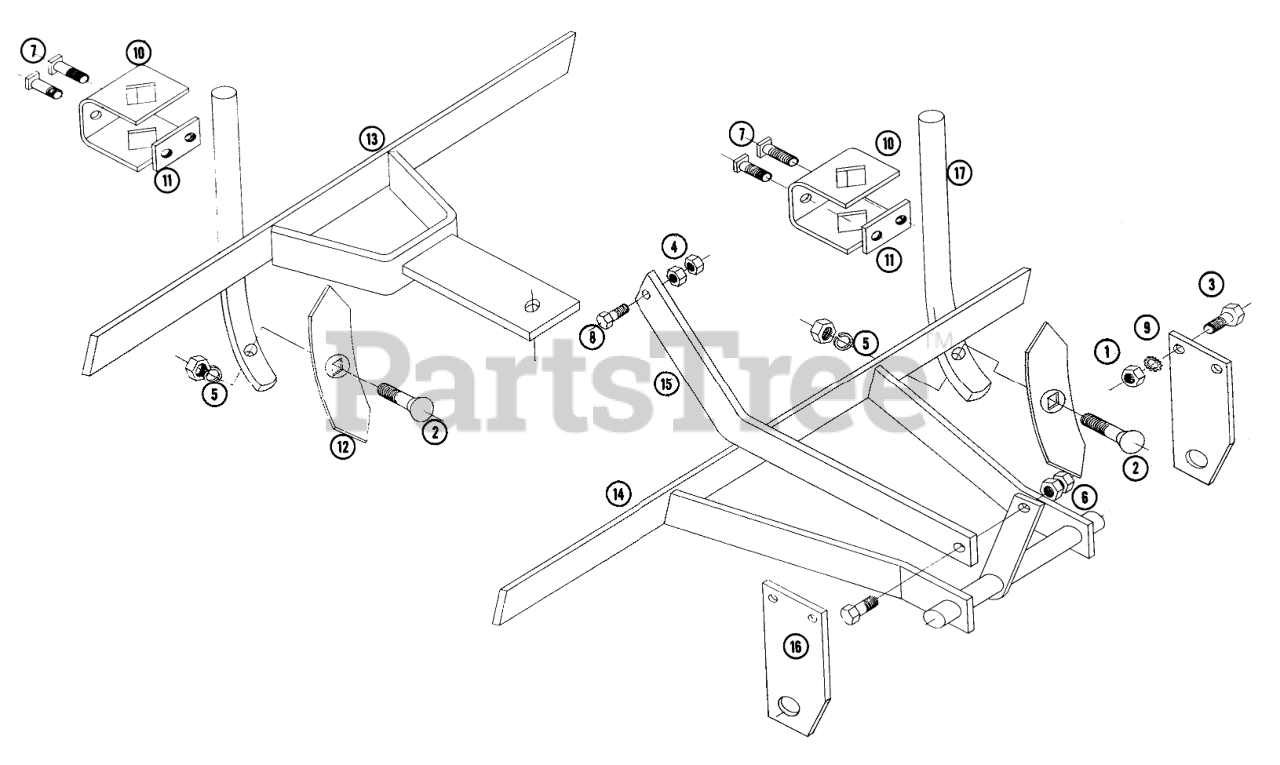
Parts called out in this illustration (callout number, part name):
1	Hex Nut
2	Bearing
3	Hex Head Cap
5	Lockwasher
6	31300 '65-67&UP 20
7	Sq. Hd. Set Screw 3/8-16 x 1 1/4
8	Hex Hd. Cap Screw
9	Shakeproof Washer 3/8
13	Rear Frame W/A
14	Front Frame W/A
15	Lift Arm
16	Plate-Mounting
